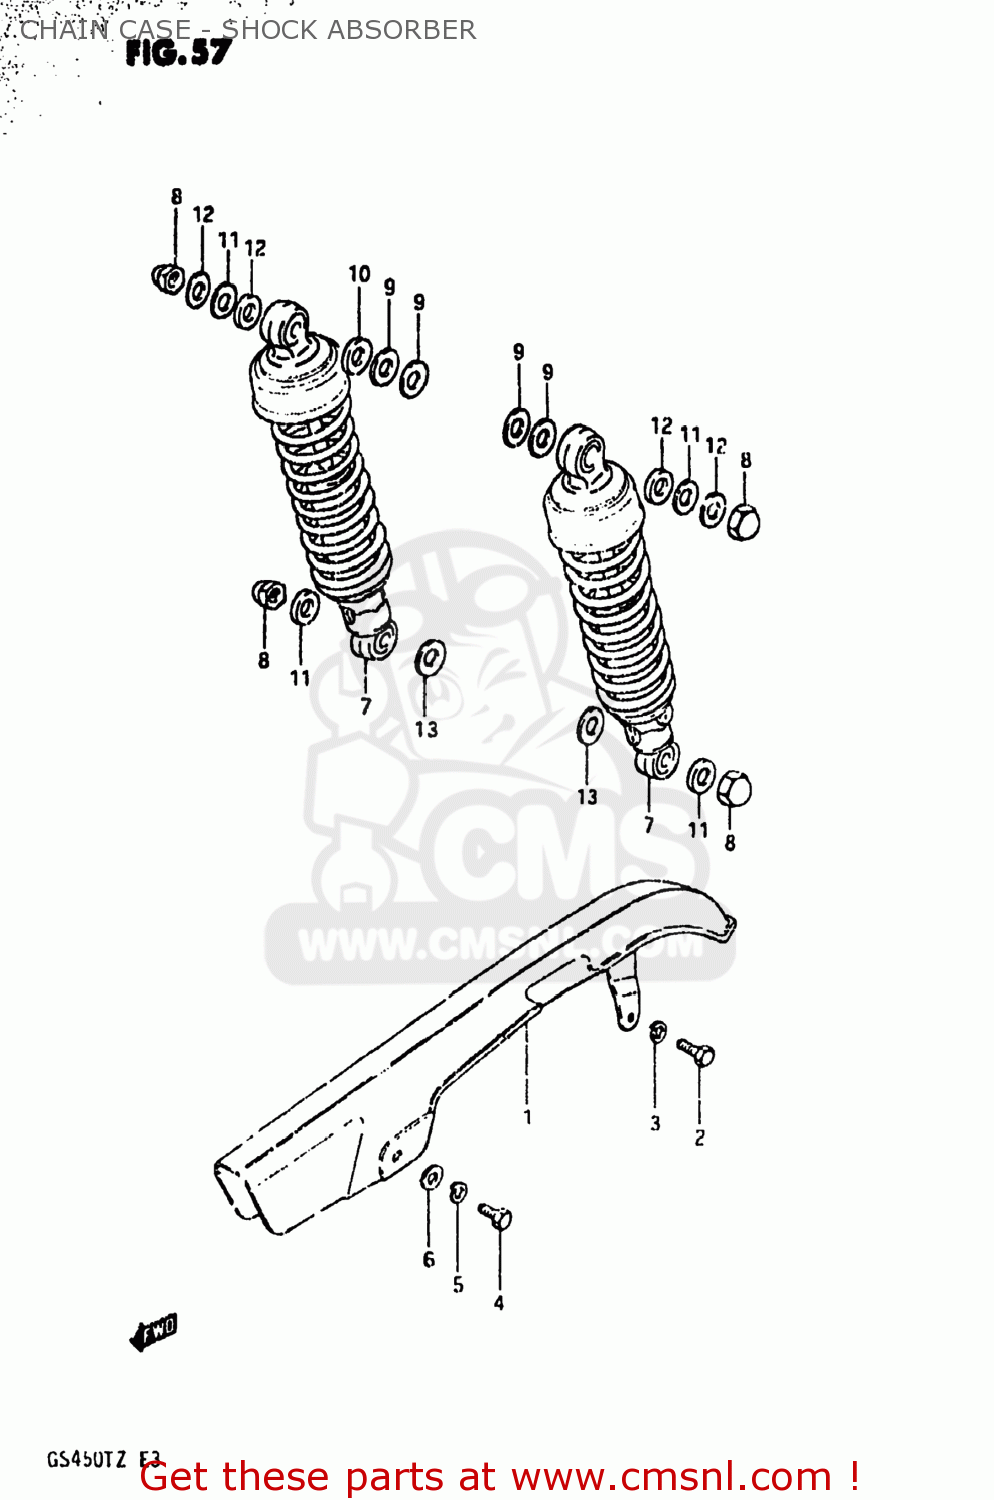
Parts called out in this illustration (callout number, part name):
1	CASE,CHAIN
2	BOLT, UPPER
3	LOCK WASHER
4	BOLT
5	LOCK WASHER
6	WASHER
7	ABSORBER ASSEMBLY,REAR SHOCK
8	NUT, LOWER LH
9	WASHER
10	WASHER (12.5X24X3.2)
11	WASHER
12	WASHER(10.5X24X3.2)
13	WASHER (12.5X24X1.6)
